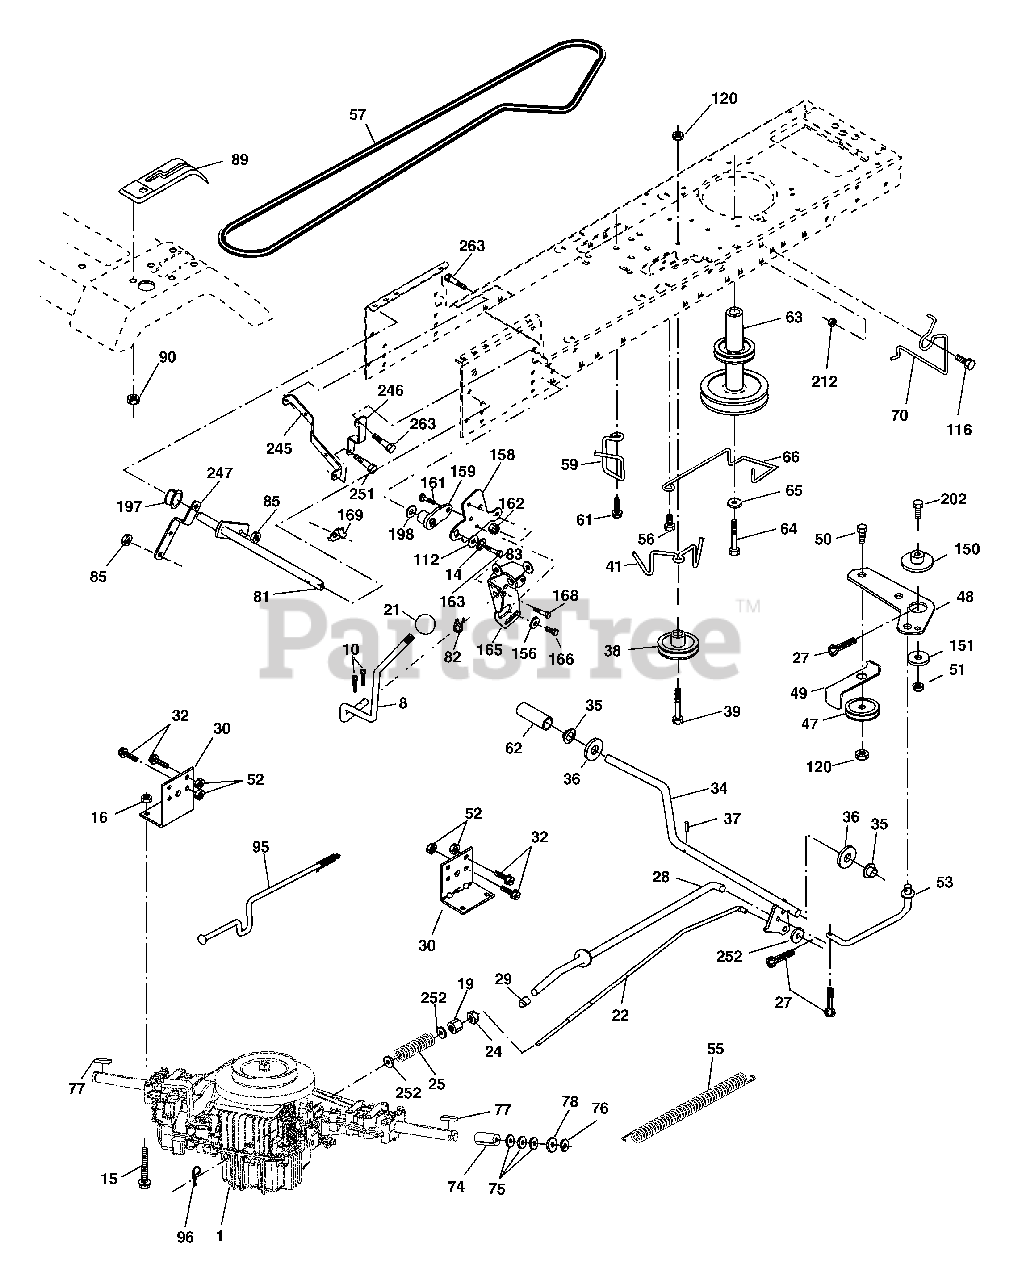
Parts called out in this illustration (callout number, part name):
10	Pin Cotter 1/8 x 1 CAD
14	Washer Lock Hvy Helical
15	Bolt, Hex FLGHD 5/16-18 Gr. 5
16	Nut Lock Hex W/Ins 5/16-18 unc
19	Nut Lock Hex W/Wsh 3/8-16 unc
21	Knob, Round 1/2-13
22	Rod, Brake Hydro
24	Nut
25	Spring, Brake Rod
27	Pin Cotter 1/8 x 3/4 CAD.
28	Rod, Parking Brake
29	Cap, Parking Brake
30	Bracket, Transaxle
32	Bolt Hex Hd 5/16-18 unc x 3/4
34	Shaft, Foot Pedal
35	Bearing, Nylon
36	Washer
37	Pin, Roll
38	Pulley, Composite
39	Bolt Rdhd 3/8-16 unc x 2-3/4 Gr. 5
41	Keeper, Belt Idler
47	Pulley, Idler, V-Groove
48	Bellcrank Clutch Grnd Drv STL
49	Retainer, Belt
50	Bolt Carr Sh 3/8-16 x 1-1/2 Gr. 5
51	Nut Crownlock 3/8-16 unc
52	Nut Crownlock 5/16-18 unc
53	Link, Clutch
55	Spring, Return, Clutch
56	Screw 3/8-16 x 1-1/4
57	V-Belt, Ground Drive
59	Keeper, Center Span
61	Screw 3/8-16 x .875
62	Cover, Pedal
63	Pulley, Engine
64	Bolt Hex 7/16-20 x 4 x Gr. 5-1.5 Thr
65	Washer
66	Keeper Belt Engine
70	Guide Belt
74	Spacer, Axle
75	Washer 25/32 x 1-1/4 x 16 Ga.
76	E-Ring
77	Key, Square
78	Washer 25/32 x 1-5/8 x 16 Ga.
81	Shaft Asm. Cross Hydro
82	Spring Torsion T/A
83	Washer 17/32 x 3/4 x 16 Ga.
85	Nut Lock Center 1/4-28
89	Console, Shift
90	Screw Hex Wsh Hi-Lo 1/4-1/2 unc
95	Disconnect Asm. Rod Bypass LTH
96	Retainer Spring 1" Zinc/Cad
112	Washer 9/32 x 3/4 x 10 Ga.
116	Bolt RDHD SQNK 3/8-16 unc x 1
120	Nut Lock Flg 3/8-16 unc
150	Spacer Retainer
151	Washer 13/32 x 2 x 10 Ga.
156	Washer Srrted 5/16 ID x 1.125
158	Bracket Shift Mount
159	Hub Shift
161	Bolt Rdhd Sqnk 1/4-20 x 3/4 Gr. 5
162	Nut Crownlock 1/4-20 unc
163	Bolt Hex Fin 1/4-20 unc x 1 Gr. 5
165	Bracket Pivot Lever
166	Screw 5/16-18 x 5/8
168	Bolt Shoulder 5/16-18 x .561
169	Plate Fastening Lt
197	Nyliner Snap-In 5/8" ID
198	Washer Nyl 7/8 ID x .105
202	Bolt Carr Sh 3/8-16 x 1-3/4 Gr. 5
212	Nut Hex flange Lock
245	Strap Torque LH
246	Strap Torque RH
247	Link Shift Transaxle
251	Screw 5/16-18 x 1
252	Washer 13/32 x 1 x 16 Ga.
263	Screw Hex Wsh Thdr 3/8-16 x 3/4
